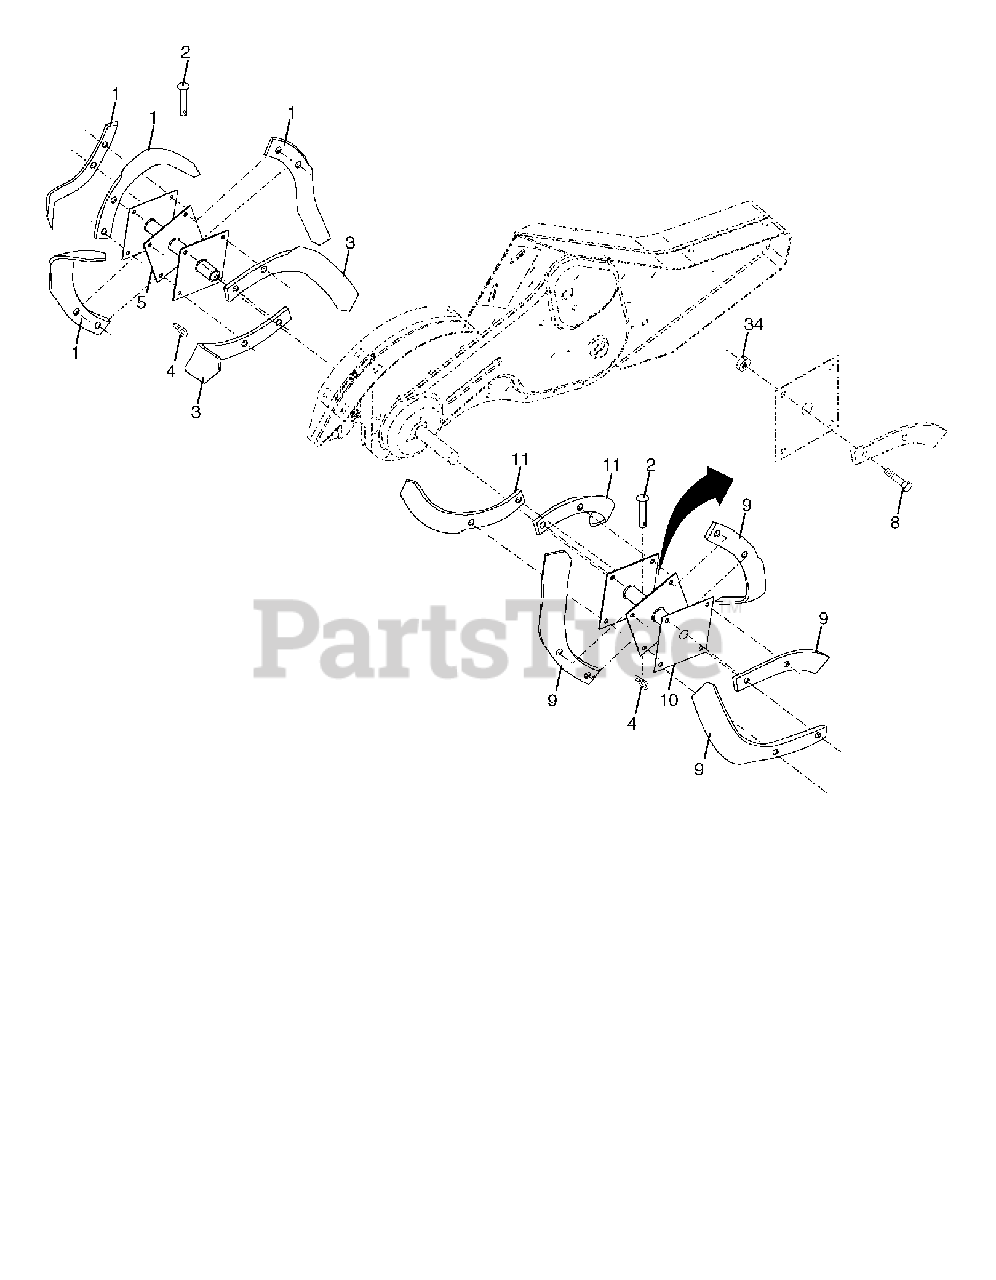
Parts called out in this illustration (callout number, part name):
2	CLEVIS PIN
3	TINE.LH.12"
5	HUB.&.PLATE.ASM.LH
8	BOLT.HEX.001X20.37-24X1.ZINC
10	HUB & PLATE ASM RH
11	TINE.RH.12"(72R)
34	NUT CROWNLOCK 3/8-24
